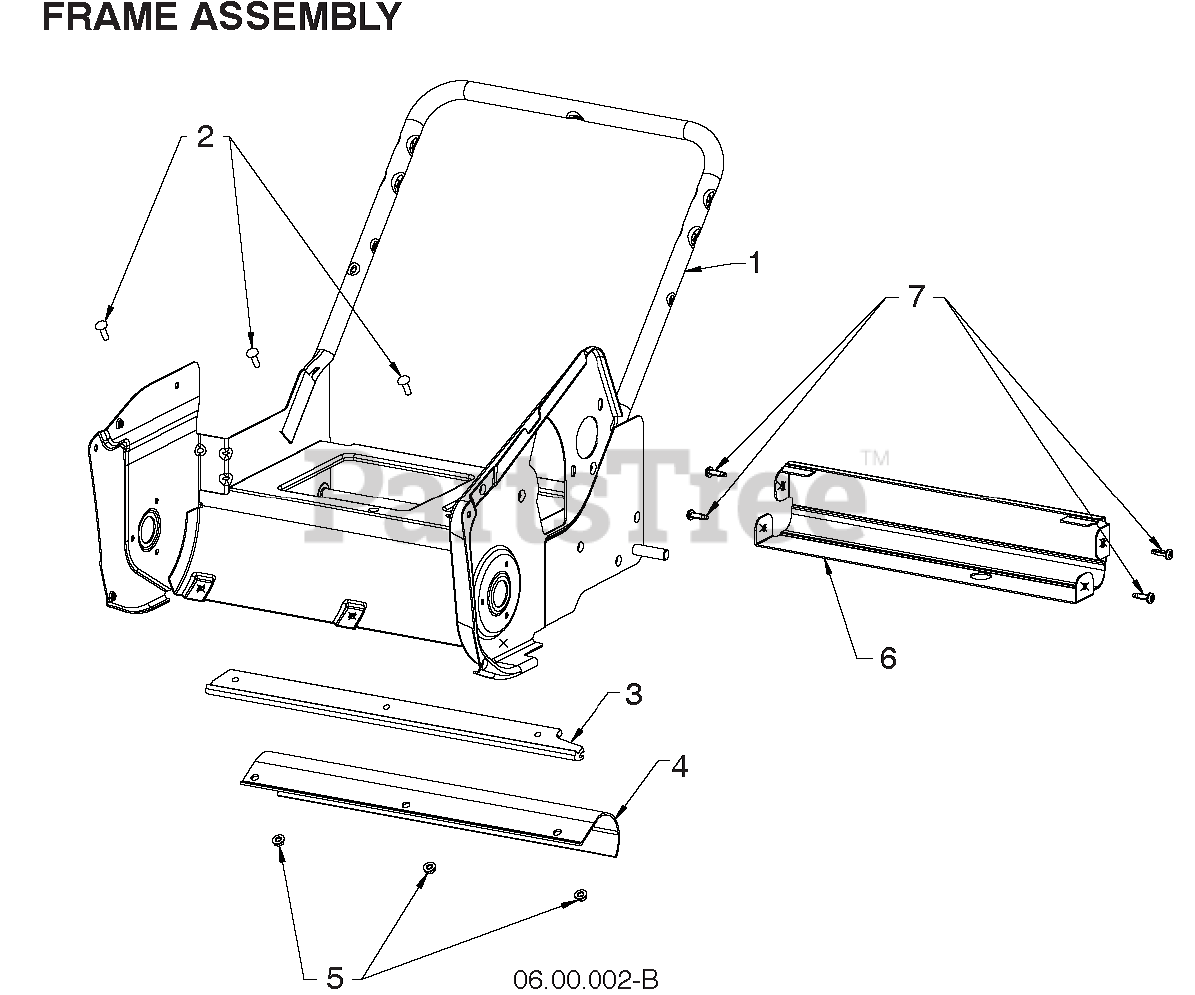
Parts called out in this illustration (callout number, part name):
1	FRAME.WELDMENT.GREY
2	BOLT.CARRIAGE.1/4-20 X 7/8
3	BAR.SCRAPER.SINGLE.STAGE.GREY
4	SKIRT.SCRAPPER-SSST
5	NUT.HEX.FLANGE.1/4
6	SUPPORT.SSST.REAR.FRAME.GREY
7	SCREW.PAN.HD.TORX.1/4-20X.750
